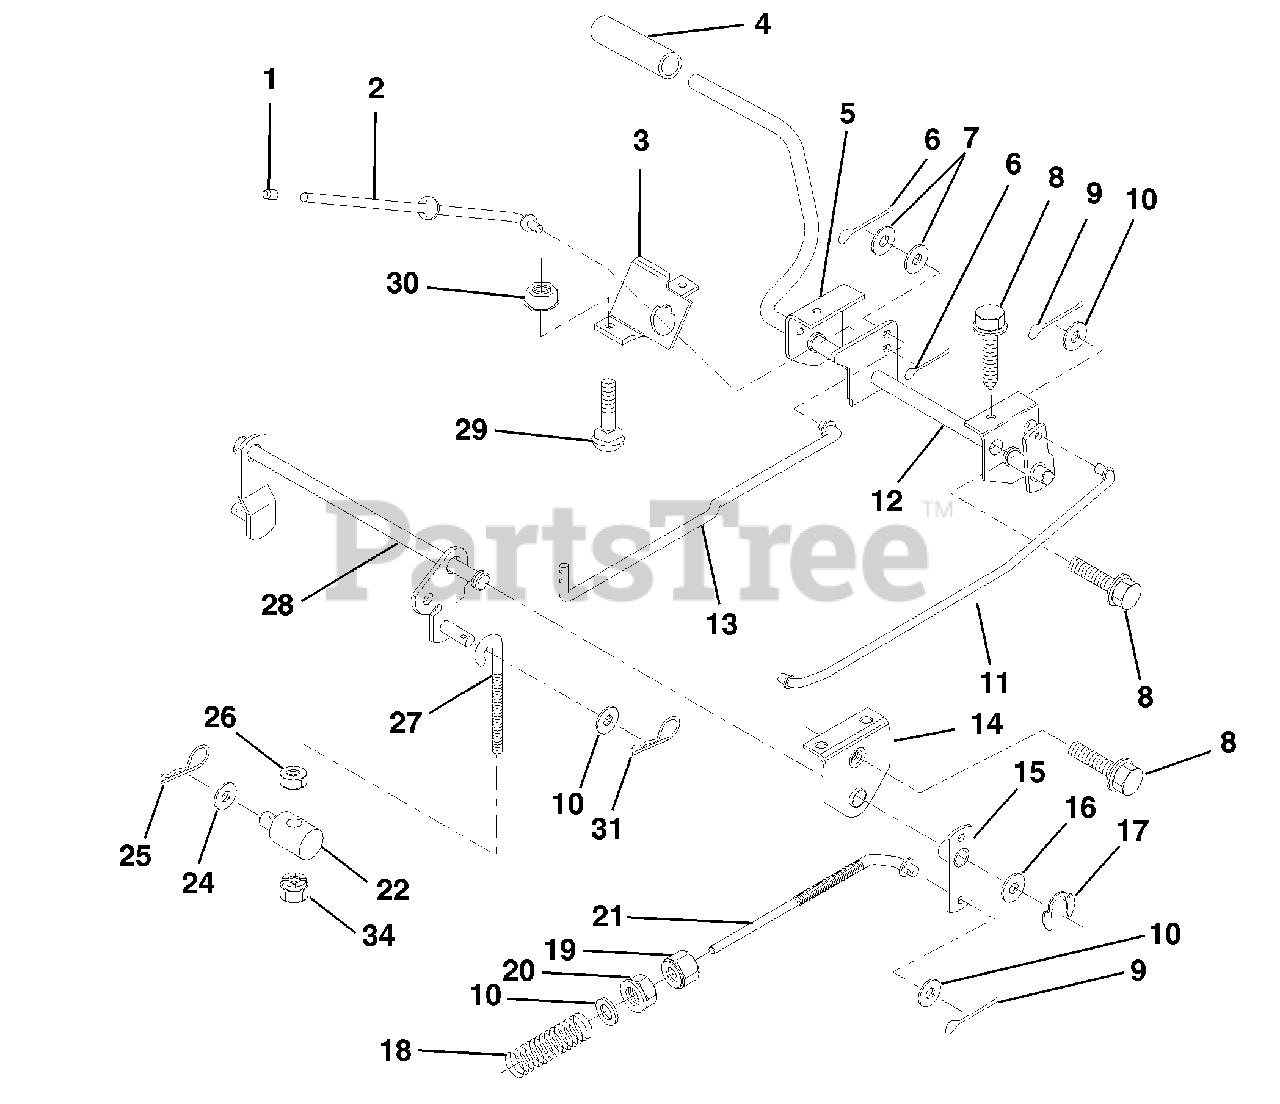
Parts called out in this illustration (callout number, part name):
1	Cap, Plunger
2	Rod, Parking Brake
3	Bracket, Parking Brake
4	Cover, Pedal
5	Bracket, Clutch/Brake Pedal, L.H.
6	Pin, Cotter 3/32 x 3/4
7	Washer 13/32 x 5/8 x 16 Ga.
8	Screw, Hex, Thd. Roll. 5/16-18 x 1/2
9	Pin, Cotter 1/8 x 3/4
10	Washer 13/32 x 13/16 x 16 Ga.
11	Rod, Brake Front
12	Assembly, Clutch/Brake Pedal
13	Rod, Clutch
14	Bracket, Lift, Shaft
15	Assembly, Brake, Pivot, Arm
16	Washer 25/32 x 1-1/8 x 16 Ga.
17	Ring, Klip
18	Spring, Brake Rod
19	Nut, Hex, Jam 3/8-16 UNC
20	Nut, Lock, hex. w/Ins. 3/8-16 INC
21	Rod, Rear Brake
22	Trunnion, Lift
24	Washer 13/32 x 1-1/4 x 12 Ga.
25	Spring, Retainer
26	Nut, Centerlock 3/8-16 UNC
27	Link, Threaded
28	Assembly, Rear Mower Lift
29	Bolt, Carriage 5/16-18 UNC x 3/4
30	Nut, Keps 5/16-16 UNC
31	Retainer Spring
34	Nut, Crownlock 3/8-16 UNC
